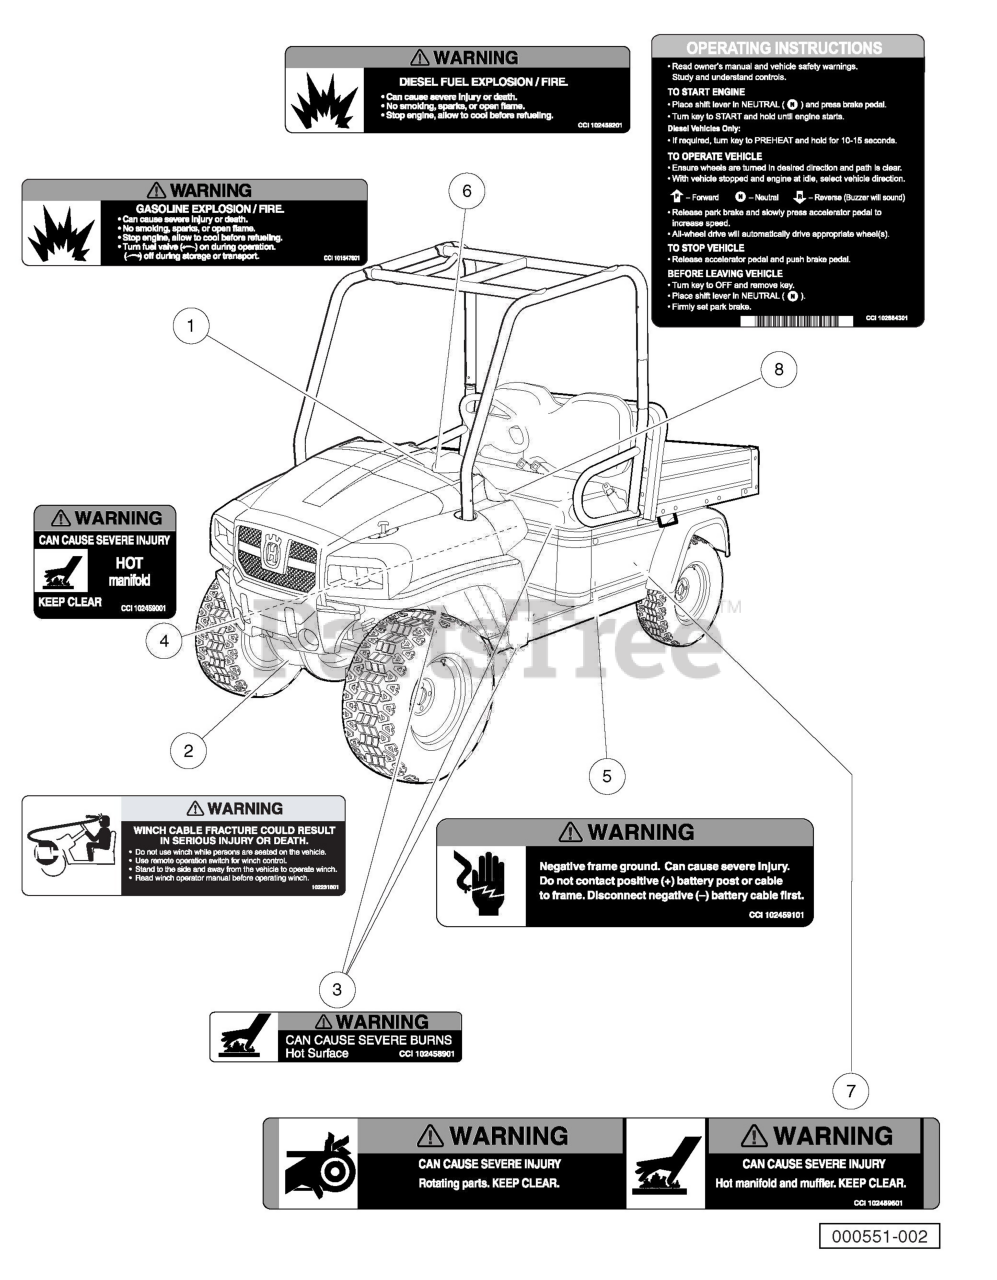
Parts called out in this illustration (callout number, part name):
1	Decal, Gasoline Explosion/Fire Warning
2	Decal, Winch Cable Fracture Warning
3	Decal, Hot Surface Warning
4	Decal, Hot Manifold Warning
5	Decal, Frame Ground Warning
6	Decal, Diesel Explosion/Fire Warning
7	Decal, Rotating Parts and Hot Exhaust Warning
8	Decal, Operating Instr, AWD
